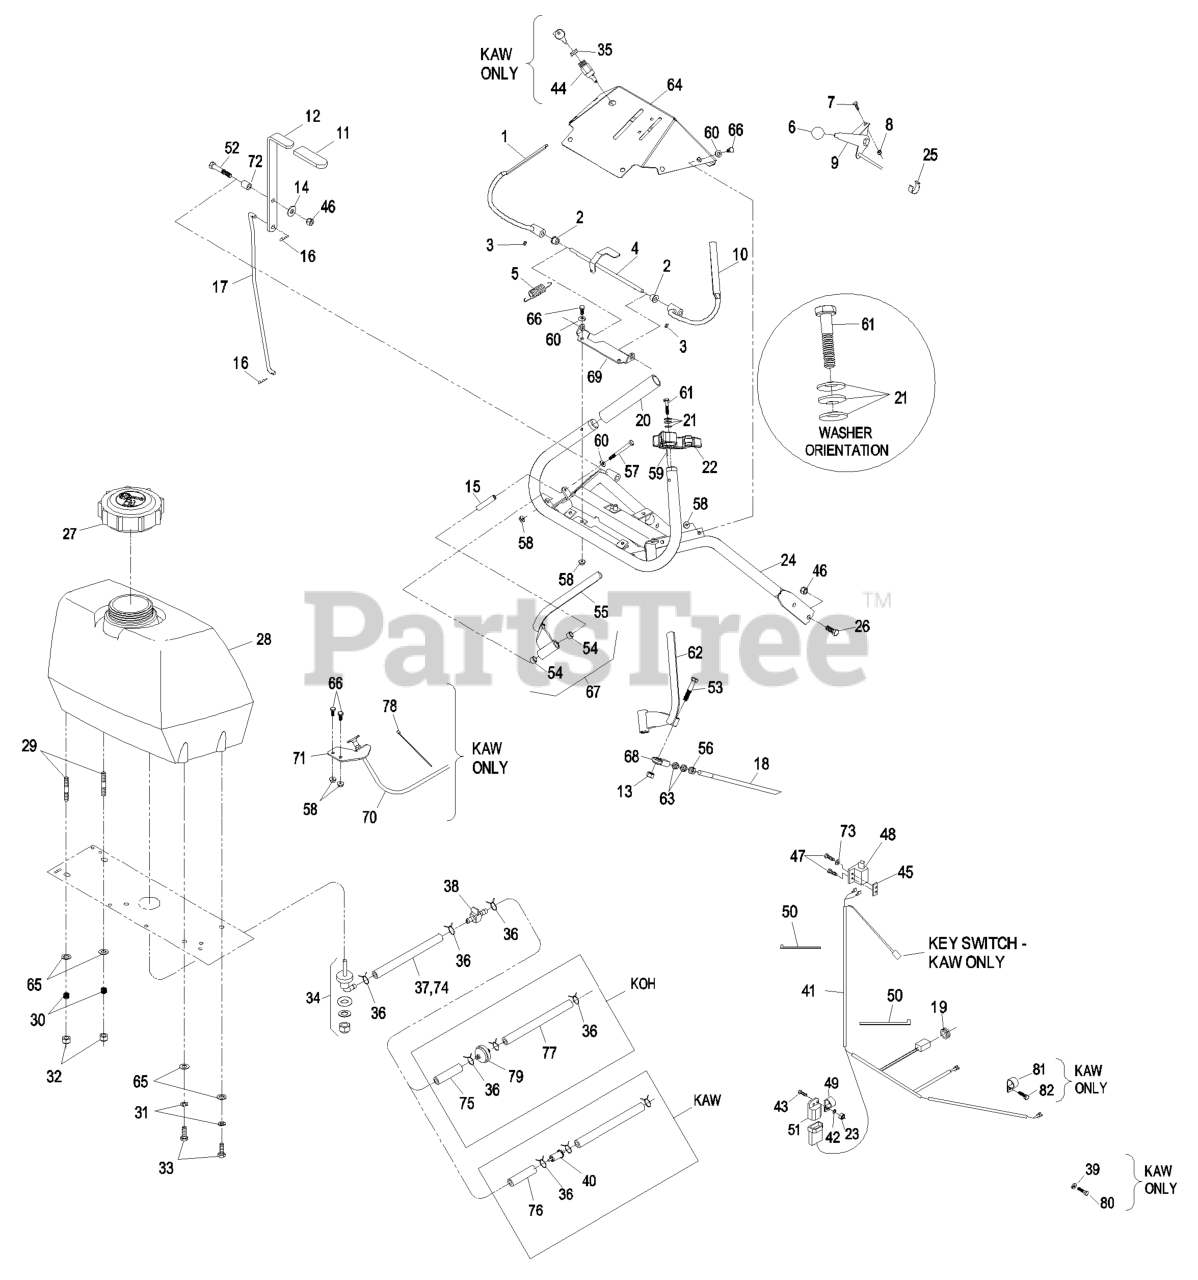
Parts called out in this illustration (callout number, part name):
2	BUSHING-NYLON
3	SCREW-SET
4	WLD,OPC LEVER AXLE
5	SPRING-EXTENSION
6	KNOB-BALL
7	BOLT-CARR
8	NUT-LOCK, NI
9	THROTTLE CABLE ASM
11	GRIP-LEVER
12	CLUTCH LEVER-W/GRIP
13	NUT-LOCK, NI
14	WASHER-FLAT
15	BUSHING-LEVER, DRIVE
16	PIN-COTTER
17	LINKAGE,UPPER BLADE (PLT)
18	LINKAGE,DRIVE (PLT)
19	GROMMET
20	GRIP-BAR, HANDLE
21	WASHER-SPRING
23	NUT-LOCK, NI
24	WLD,UPPER ECS HANDLE
25	CLIP-CABLE
26	SCREW-HH
28	ASM,FUEL TANK W/B
29	STUD
30	SPRING-TANK, FUEL
31	WASHER-LOCK
32	NUT-LOCK, NI
33	SCREW-HH
34	FITTING-FUEL, BULKHEAD
35	NUT-SWITCH, IGNITION
37	HOSE-FUEL
38	VALVE-FUEL
39	WASHER-LOCK
40	Kawasaki Pn 41019-1055 W/6" Fuel Line
41	HARNESS-WIRE
42	WASHER-FLAT
43	SCREW-HH
44	SWITCH & KEY (INCLUDES NU
45	PLATE-TAPPED
46	NUT-LOCK, NI
47	SCREW-PPH
48	SWITCH-OPEN, NORMALLY
49	CLIP-LOOM
50	TIE-CABLE
51	MODULE-INTERLOCK
52	SCREW-CARR
53	SCREW-HH
54	BUSHING-SLEEVE
56	NUT-HEX
57	SCREW-HH
60	WASHER-FLAT
61	SCREW-HH
63	NUT-HJ
64	ASM,CONSOLE W/DECALS
65	WASHER-PLAIN
66	SCREW-HH
67	DRIVE LEVER-ASM, RH
68	JOINT-BALL, END
69	BRACKET,OPC AXLE
70	CABLE-CHOKE
71	BRACKET-CABLE, CHOKE
72	BUSHING-LEVER, LIFT
73	WASHER-FLAT
74	HOSE-FUEL
75	HOSE-LINE, FUEL
76	HOSE-FUEL
77	HOSE-LINE, FUEL
78	TIE-PLASTIC
80	SCREW-HH
81	CLIP-LOOM
82	SCREW-HH
